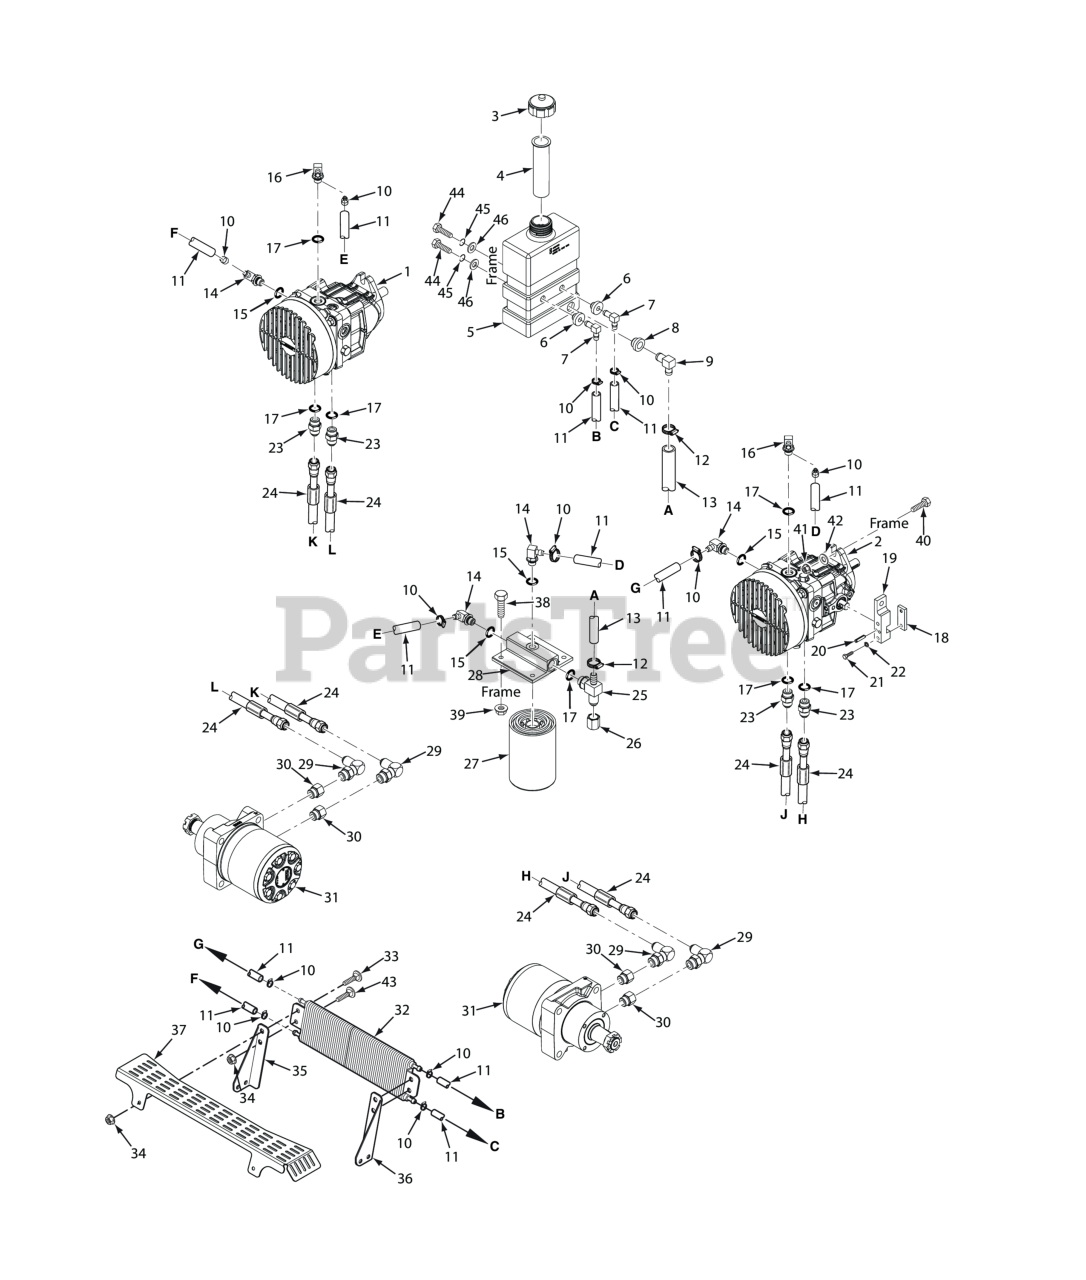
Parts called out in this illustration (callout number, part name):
1	Pump w/Fan, Right Hand (791DFI,35BVAC)
2	Pump w/Fan, Left Hand (791DFI, 35BVAC)
3	CAP, HYDRAULIC TANK
4	Insert, Filler Neck
5	Hydraulic Tank Assy., STTII
6	Bushing, 0.56" Dia. Viton
7	Elbow, 90 Degree, 9/16-18 JIC x 9/16 O-Ring
8	Bushing, 0.78" Dia. Viton
9	Fitting, 90 Degree - 1/2" Hose
10	Clamp, .69" Max. / .25" Min. Dia.
11	Hose, 3/8" ID - 10-1/4" Long (Order By The Inch)
12	Clamp, Cable 3/4" I.D.
13	Hose Assembly, 1/2" ID (Oil Reservoir to Filter Base)
14	Elbow, 90 Degree - 9/16" O-Ring x 3/8" Hose
15	"O" RING, 5/64 X 15/32 ID
16	Elbow, 90 Degree - 3/4" O-Ring x 3/8" Hose
17	"O" RING, 3/32 X 5/8" ID
18	Clamp Plate, Pump Control
19	Block, RH Pump Control
20	Roll Pin, Spring 3/16 x 3/4"
21	Bolt, Hex Head, 1/4-20 x 1-1/2"
22	Lockwasher, 1/4� Spring
23	Fitting, Union 3/4-16 JIC X O-Ring
24	Hose Assembly
25	Tee, 3/8" O-Ring x JIC x 1/2" Hose
26	CAP, 3-4-16 JIC
27	FILTER, SPIN-ON LUBE
28	Filter Head Assembly
29	ELBOW, 90DEG, 7/8-14 JIC X 7/8-14 O-RING
30	Bushing, 7/8"-14 JIC x 3/4"-16 O-Ring
31	Wheel Motor, Parker TG - 18ci.
32	Cooler, Transmission
33	Serr. Fl. Hex Head CPSCR, 1/4-20 x 3/4"
34	NUT, 1/4-20 SERRATED FLANGE HEX HEAD
35	Mounting Bracket, Cooler - RH
36	Mounting Bracket, Cooler - LH
37	Screen Guard, Briggs & Stratton 37BV-EFI
38	Bolt, Heax Head 5/16-18 x 1" (48V / 52V)
39	Nut, Serrated Flange 5/16-18 (Right Front Engine Mounting, Briggs and Kohler Only)
40	Bolt, Hex Head 3/8-16 x 1-1/2" B&S 32BV
41	HEX NUT, ELASTIC STOP LOCK, 3/8-16
42	Flatwasher, 3/8 (.391 x .938 x .105 HD) Grade 8
43	Bolt, Carriage 1/4-20 x 1/2"
44	BOLT, SERRATED FLANGE HEX HEAD 5/16-18 X 3/4"
45	Lockwasher, 5/16 (.317 x .586 x .078) Helical Spring
46	Flatwasher, 5/16-.375 x .875 x .083 (35BV & 37BV-EFI)
